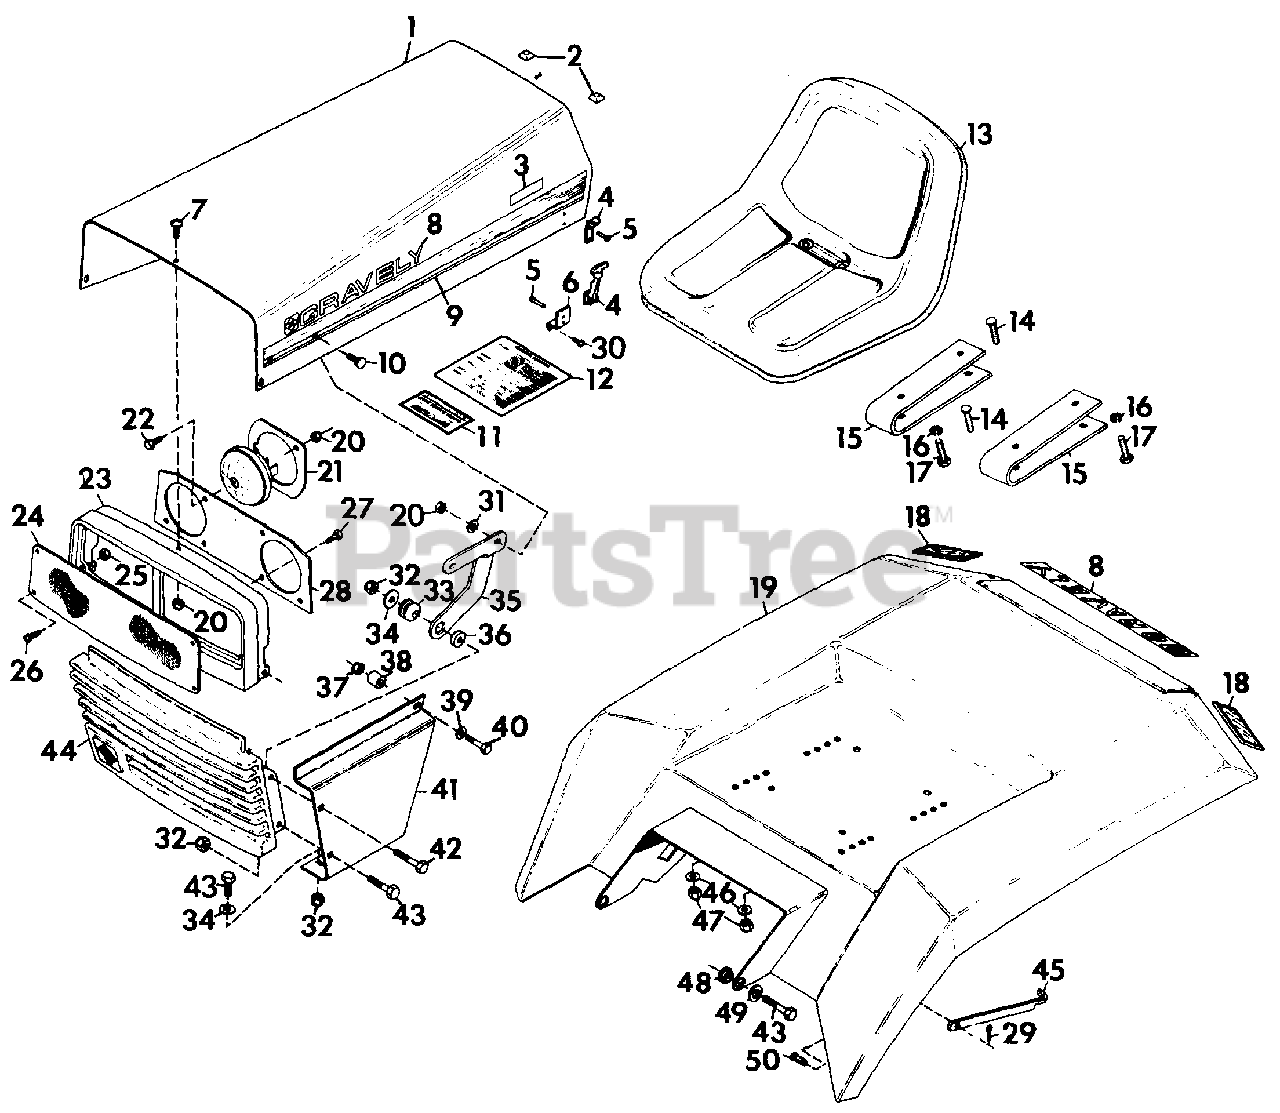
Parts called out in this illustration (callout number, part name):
1	HOOD, TRACTOR
2	STOP
3	DECAL, MODEL 8122-G
3	DECAL, MODEL 8123-G
3	DECAL, MODEL 8163-G
3	DECAL, MODEL 8179-G
3	DECAL, MODEL 8199-G
4	LATCH, FLEXIBLE
5	RIVET, DOME HEAD
6	BRACKET, HOOD LATCH MOUNTING
7	SCREW, MACHINE 1/4-20 PHD
8	DECAL, GRAVELY LOGO
9	DECAL, SIDE STRIPE L.H. AND R.H.
10	BOLT, 1/4-20X.75 RD HD SQ NK
11	DECAL, ELECTRICAL SYSTEM WARNING
12	DECAL, MAINTENANCE
13	SEAT, HIGH BACK
14	BOLT, CARRIAGE 5/16-18X.75
15	SPRING, SEAT
16	WASHER, LOCK 5/16 REG.
17	BOLT, HEX 5/16-18X.75
18	REFLECTOR, RED SAFETY
19	WELDMENT, SEAT PAN
19	WELDMENT, SEAT PAN NOTCHED
20	NUT, LOCK 1/4-20
21	RING, HEADLIGHT RETAINER
22	BOLT, HEX 1/4-20X1.00
23	BEZEL, HEADLIGHT
24	PANEL, HEADLIGHT LENSE
25	NUT, LOCK 10-24
26	SCREW, MACHINE 10-24X.75 PHD
27	SCREW, TAPPING 1/4-20X.625 HHDST
28	PANEL, HEADLIGHT REFLECTOR
29	PIN, COTTER .06X.75
30	SCREW, 8-18X.375 PHD CR
31	WASHER, FLAT .281X.625X.065
32	NUT, LOCK 3/8-16
33	GROMMET
34	WASHER, FLAT .438X1.000X.083
35	HINGE, HOOD L.H.
35	HINGE, HOOD R.H.
36	SPACER
37	NUT, LOCK 5/16-18
38	SPACER, .375X.100X1.00
39	WASHER, FLAT .344X.688X.065
40	BOLT, HEX 5/16-18X1.75
41	PANEL, SIDE L.H.
41	PANEL, SIDE R.H.
42	BOLT, HEX 3/8-16X2.00
43	BOLT, HEX 3/8-16X1.00
44	CASTING, GRILLE
45	STRAP, FENDER HOLD-UP
46	WASHER, FLAT .375X1.125X.065
47	NUT, LOCK 5/16-18
48	BUSHING, REAR FENDER
49	WASHER, FLAT .406X.812X.065
50	PIN, CLEVIS .250X.406
NS	DECAL, AMERICA
